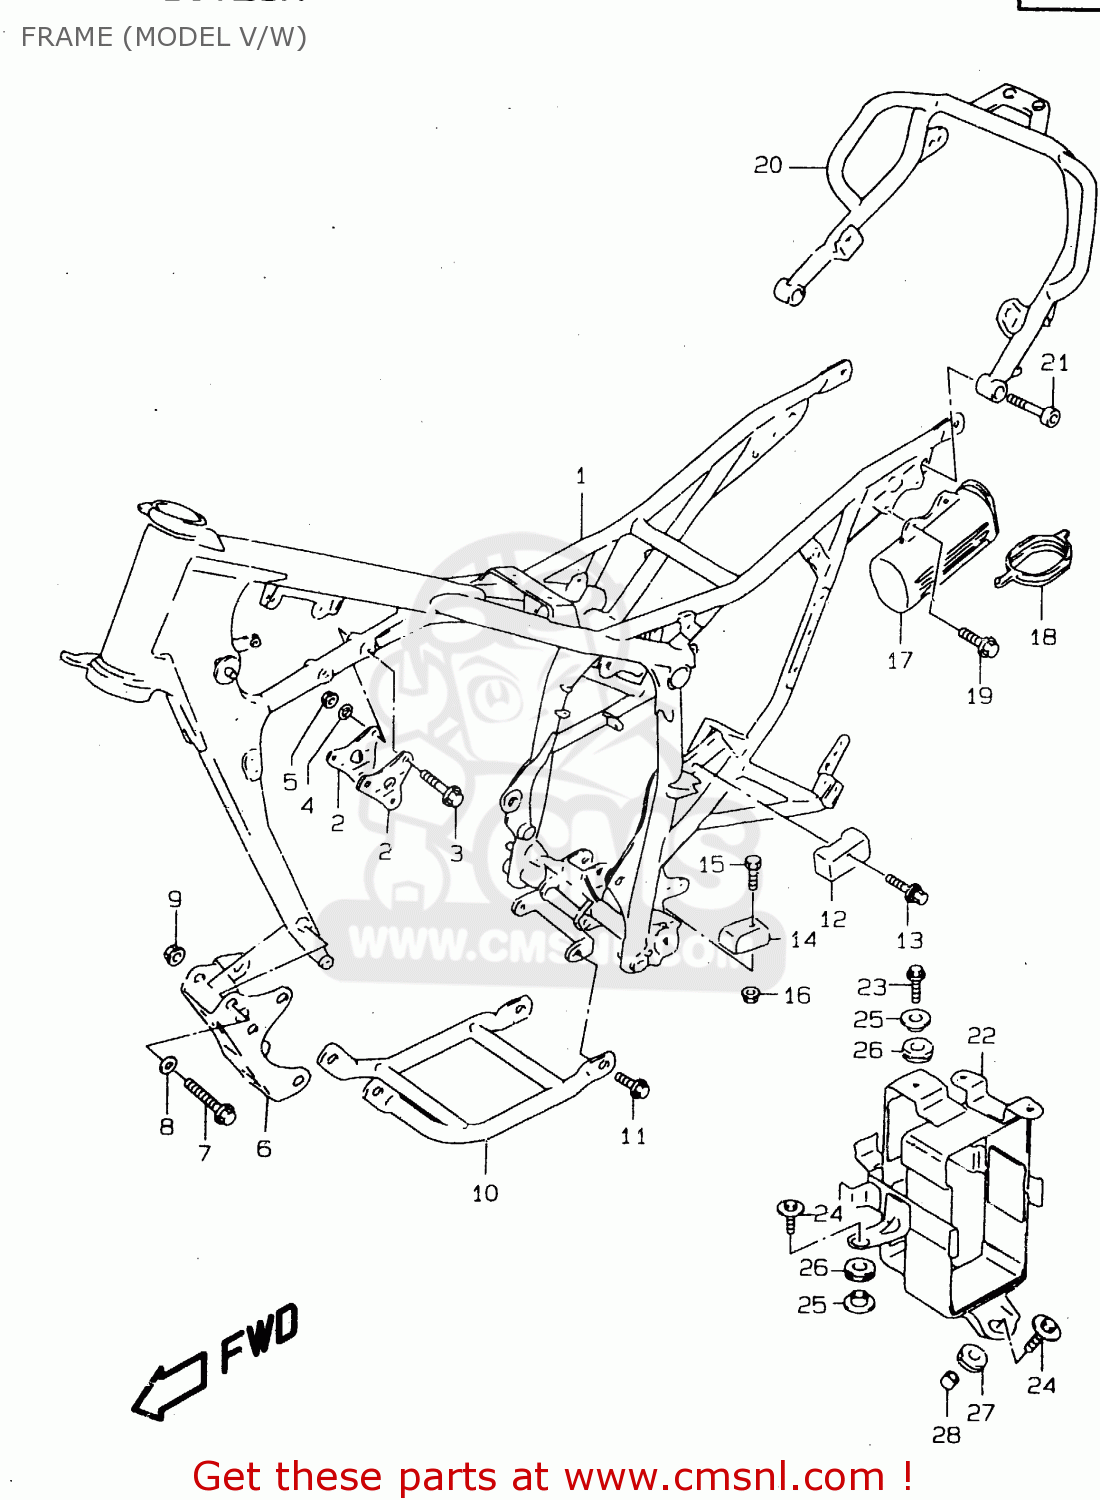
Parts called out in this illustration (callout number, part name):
1	FRAME COMP
2	PLATE,ENGINE MOUNT UPR
3	BOLT(8X53)
4	LOCK WASHER
5	NUT
6	PLATE,ENG MTG LWR
7	BOLT(8X65)
8	LOCK WASHER
9	NUT
10	PROTECTOR COMP,ENGINE
11	BOLT
12	GUIDE,CH CONTROL UPR
13	BOLT
14	GUIDE,CH LENGTH CONTROL LWR
15	BOLT
16	NUT
17	HOLDER,TOOL
18	CAP,HOLDER
19	BOLT 6X16
20	GRIP,RR
21	BOLT(8X30)
22	HOLDER,BATTERY
23	BOLT
24	BOLT(6X25)
25	WASHER
26	CUSHION
27	CUSHION
28	SPACER(6.5X10X9)
